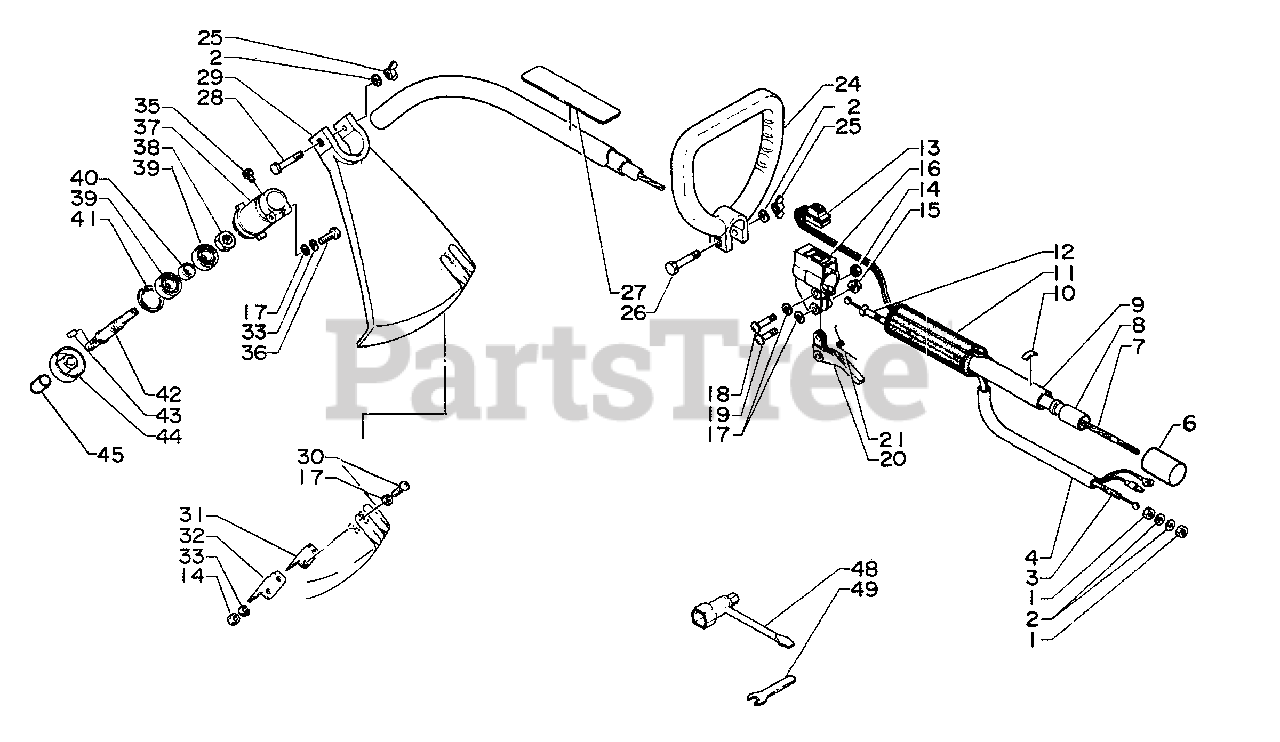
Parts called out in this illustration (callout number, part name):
2	WASHER - 6
3	CABLE, THROTTLE
4	TUBE
6	Cap, housing
7	DRIVESHAFT - FLEXIBLE
8	BUSHING
9	PIPE, MAIN
10	LABEL - ALIGNMENT
11	GRIP, HANDLE
12	GUIDE, CABLE
13	IGNITION SWITCH ASSY
15	LOCKNUT - 5
16	BRACKET, THROTTLE
17	WASHER - 5
18	SCREW - 5X30
19	SCREW - 5X30
20	TRIGGER, THROTTLE
21	SPRING, TRIGGER
24	HANDLE ASSY
25	WINGNUT - 6
26	BOLT - 6X40
27	LABEL - CAUTION
28	BOLT - 6X50
29	SHIELD, DEBRIS - PLASTIC
30	SCREW - 5X14
31	KNIFE, TRIMMER LINE
33	LOCKWASHER - 5
35	SCREW - 4X10
36	BOLT - 5X25
37	CASE, GEAR
38	NUT - 12 -- LEFT HAND
39	BEARING, BALL - 6001 DDU
41	RING, RETAINING - 28
42	GEAR - SHAFT
43	PIN - 3X6
44	ADAPTOR, BLADE - UPPER
45	CAP, DRIVESHAFT
48	T-WRENCH - 8X19mm
49	SPANNER - 10mm
